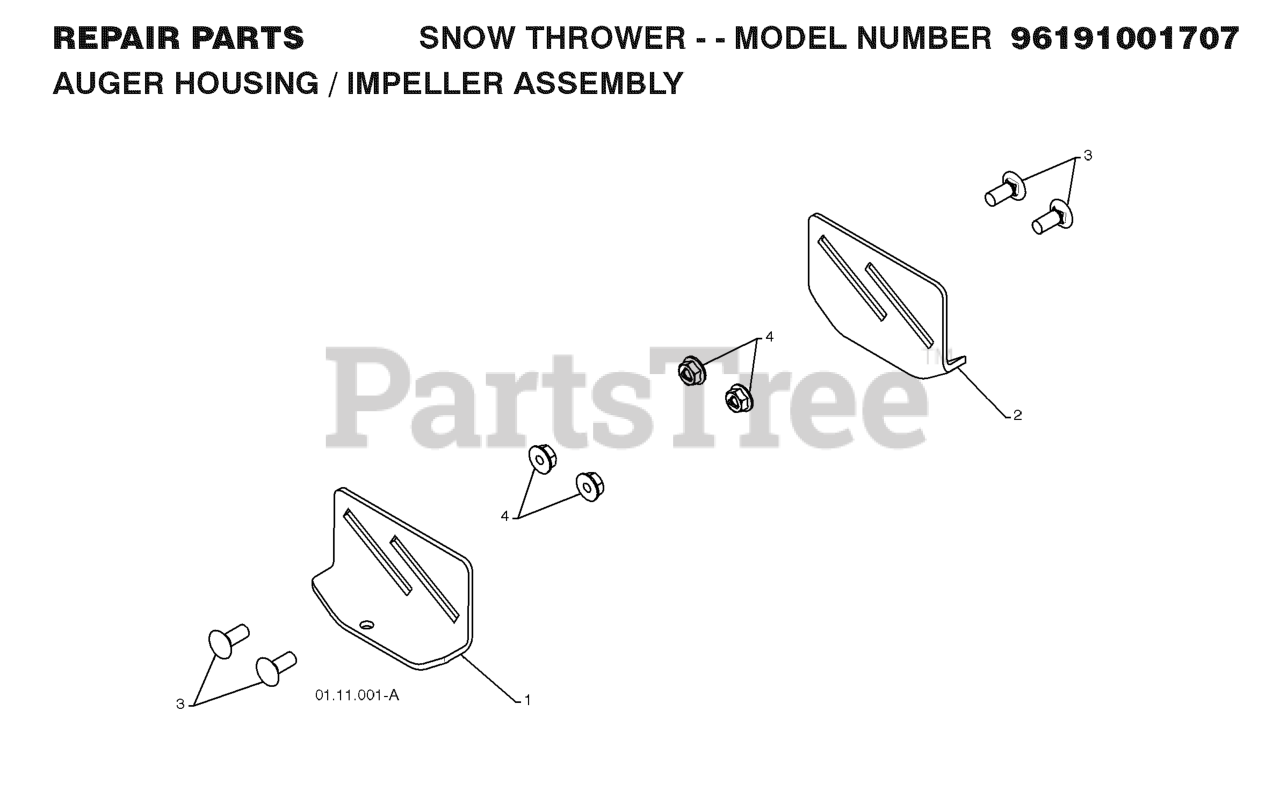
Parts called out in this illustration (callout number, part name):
1	SKID PLATE LH
2	SKID PLATE RH
3	BOLT
4	NUT.LOCK.5/16-18
